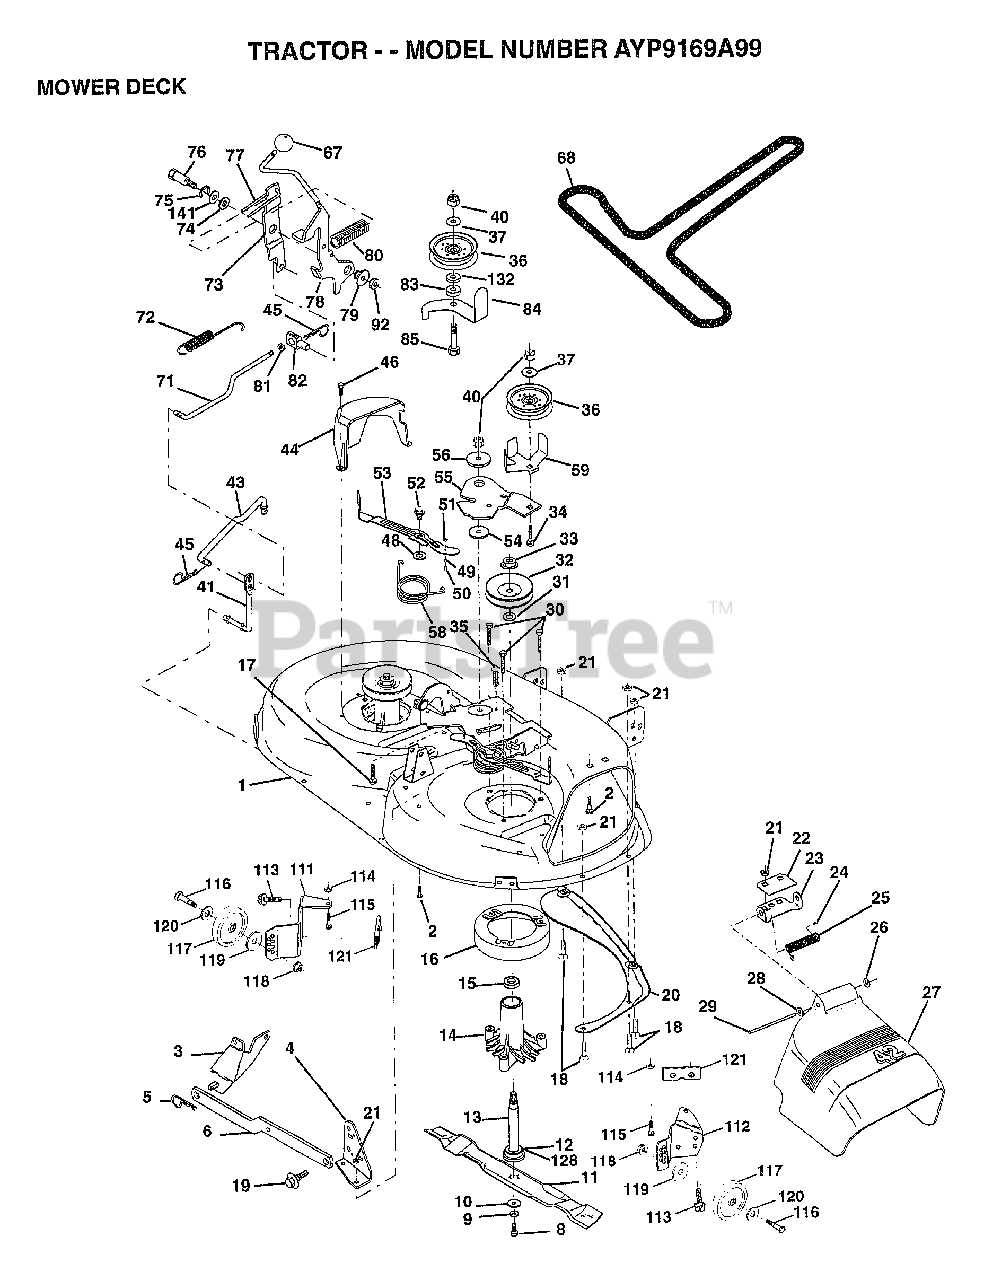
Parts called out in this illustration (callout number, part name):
1	"HOUSING ASSY.42"""
2	BOLT
3	BRKT ASM SWAY BAR
4	BRKT DECK SW BAR
8	BLADE BOLT
10	WASHER.HARD.BLADE
11	"BLADE.42"" MULCHER"
12	BEARING.BALL
14	HSG ASM MANDREL
15	BEARING
16	STRIPPER RND MWR
17	BOLT RDHD 3/8-16
18	BOLT
19	BOLT SHD 5/16-18
20	BAFFLE VORTEX 42
22	STIFFENER BRKT
23	DEFLECTOR BRKT
24	CAP-SLEEVE LT
25	SPRING TORSION
26	NUT PUSH M
27	DEFLECTOR.SHIELD
28	WASHER
29	HINGE ROD
30	"SCREW-THD ROLL,WA"
31	WASHER
32	PULLEY.MANDREL.42
34	BOLT
35	XMAS TREE FASTNER
36	FLAT IDLER PULLEY
37	WASHER
41	PIVOT ROD
43	ROD CLUTCH W/NIBS
44	GUARD MAND LH BLK
45	RETAINER M
46	SCREW.1/4-20X5/8
48	HARD SMALL WASHER
49	ROLLER ASM-CAM
50	SHOULDER BOLT
51	LOCKNUT
52	BOLT.SHLD.5/16-18
53	BRAKE PAD ARM ASM
54	HARDENED WASHER
55	ARM-IDLER
56	SPACER RETAINER
58	SPRING TORSN BRAK
59	GUARD IDLER TUV
67	KNOB.RD.7/16-14
68	BELT.V.T-PATH
71	ROD CLUTCH 38/42
72	RETURN SPRING
73	CLUTCH ARM SECOND
74	WASHER
75	RING
76	SHOULDER BOLT
77	SPRING KEEPER
78	LEVER.ASM.CLUTCH
79	BUSHING
80	SPRING.CLUTCH.MWR
81	TRUNION ADJ
82	NUT
83	WASHER
84	"KEEPER-BELT,FIXED"
85	BOLT
92	NUT
111	BRACKET.GWHL.LH.
112	BRACKET.GWHL.RH.
113	SCREW
116	BOLT M
117	WHEEL.GAGE.BLK.PL
118	LOCKNUT
119	WASHER
120	WASHER
121	BRACKET.EXTRD.GWL
128	WASHER.FELT.
132	WASHER GT
141	WASHER .T
